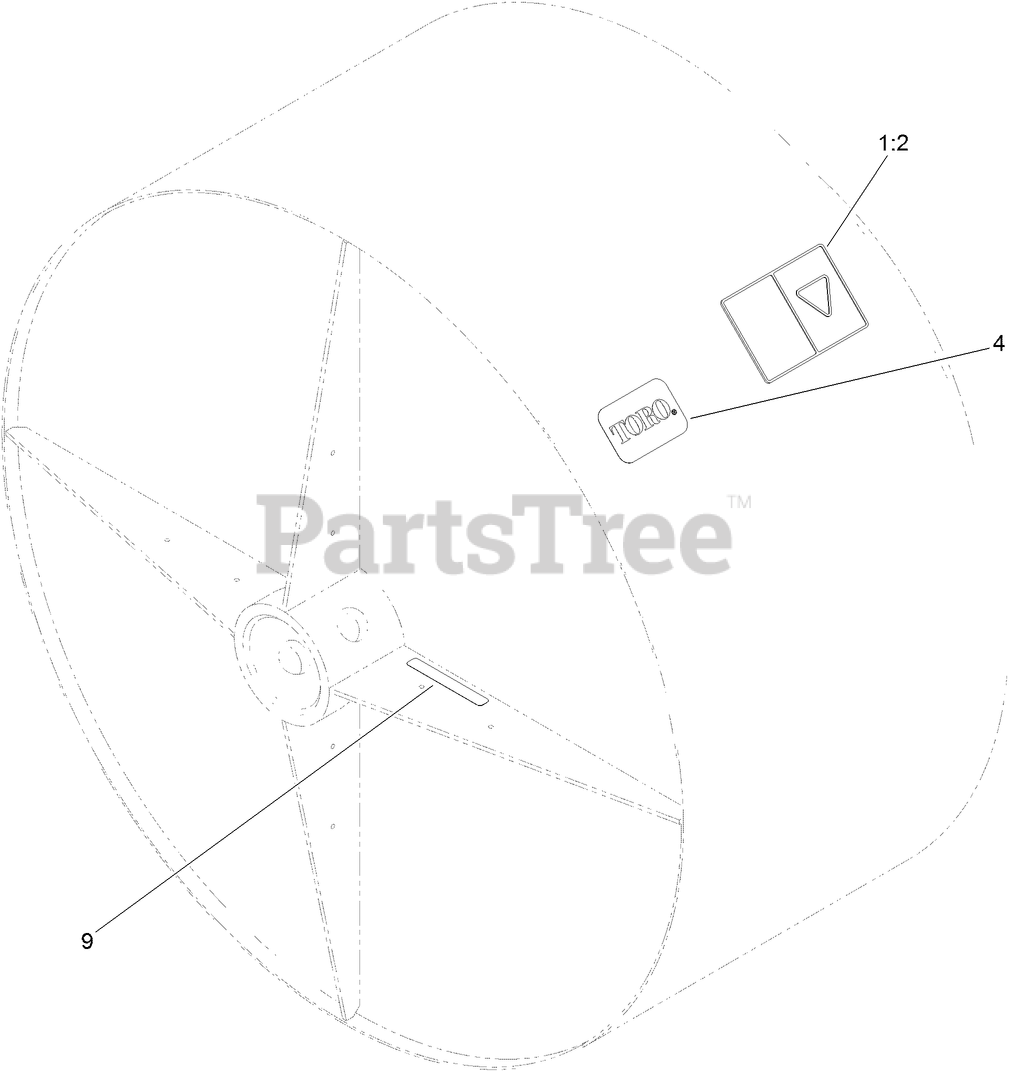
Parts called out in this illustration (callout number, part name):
1:2	DECAL-LOAD CAPACITY
4	DECAL
9	DECAL-WARNING
